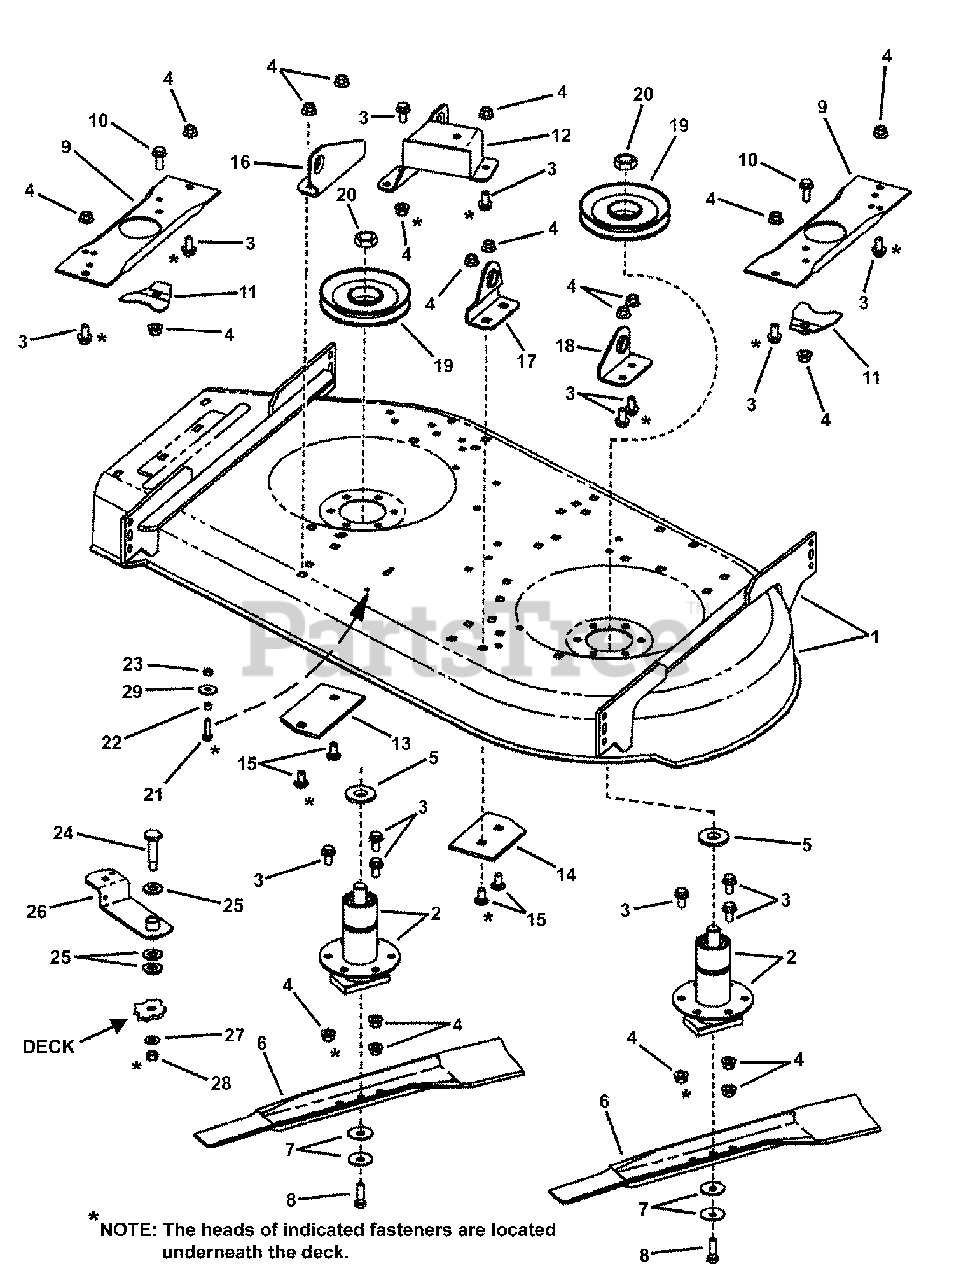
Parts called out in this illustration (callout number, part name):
1	* DECK, 42" Replacement
2	ASSEMBLY, Spindle Brake
3	BOLT, 3/8-16 x 3/4" Hex Flange Lock, GR5
4	NUT, 3/8-16 Hex Flange Lock
5	WASHER, Spindle
6	BLADE, 21 Inch Standard Lift
7	WASHER, Cone
8	SCREW, 3/8-24 x 1-1/4" Hex Head Cap, GR5
9	BRACE, Spindle
10	BOLT, 3/8-16 x 1" Hex Flange Lock
11	ASSEMBLY, Spindle Lock (press fit)
12	WELDMENT, Stationary Idler
13	REINFORCEMENT, Right Hand
14	REINFORCEMENT, Left Hand
15	BOLT, 3/8-16 x 3/4" Short Neck Carriage
16	BRACKET, Right Front Deck Lift
17	BRACKET, Left Front Deck Lift
18	BRACKET, Left Rear DeckLift
19	PULLEY, 5-1/4"
20	NUT, 3/4-16 Hex Jam, GR 8
21	BOLT, 1/4-20 x 1-1/8" Hex Flange Lock, GR5
22	SPACER, .26 x .375
23	NUT, 1/4 - 20 Hex Center Lock (replaces 91099)
24	BOLT, 3/8-24 x .62 Shoulder
25	WASHER, .531 x 1.062 x .121 SAE Flat
26	WELDMENT, Idler Arm
27	WASHER, 3/8" SAE Flat
28	NUT, 3/8-24 Hex Center Lock
29	WASHER, .27 x 1.0 x .065 Flat
